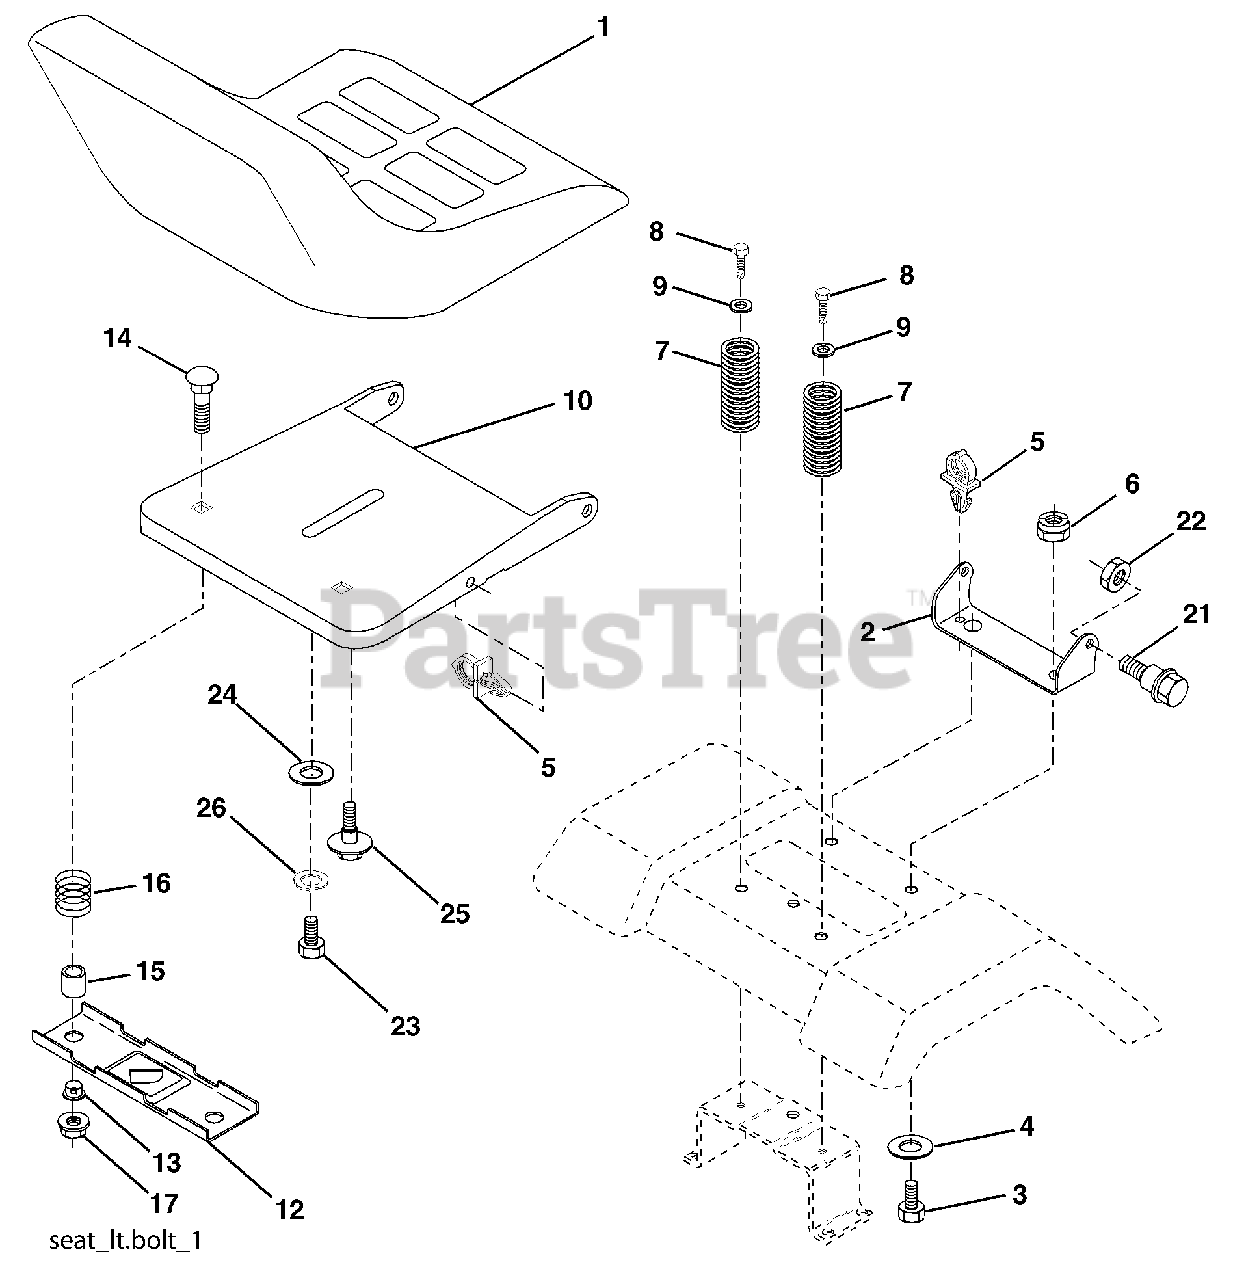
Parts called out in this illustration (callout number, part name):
1	Seat
2	Bracket Pnt Pivot Seat (blk)
3	Bolt
4	Washer 13/32 x 1 x 10 Ga
5	Clip Push-In Hinged
6	Nut
7	Spring Seat Cprsn 2 250 Blk Zi
8	Screw 3/8-16 x 1.5
9	Washer 13/32 x 1 x 14 Ga
10	Pan Pnt Seat (blk)
12	Bracket Pnt Mounting Switch
13	Bushing Snap Blk Nyl 50 Id
14	Bolt Rdhd Sht Nk 1/4-20 x 1-1/2
15	Spacer Split 28 x 96 Yel Zinc
16	Spring Cprsn 1 27 Blk Pnt
17	Nut Lock 1/4 Lge Flg Gr 5 Zinc
21	Bolt Shoulder 5/16-18 Unc Blkz-2A
22	Nut
23	Bolt Hex Black
24	Washer 17/32 x 1-3/16 x 12 Ga
25	Bolt Shoulder 5/16-18 x 62
26	Lockwasher
